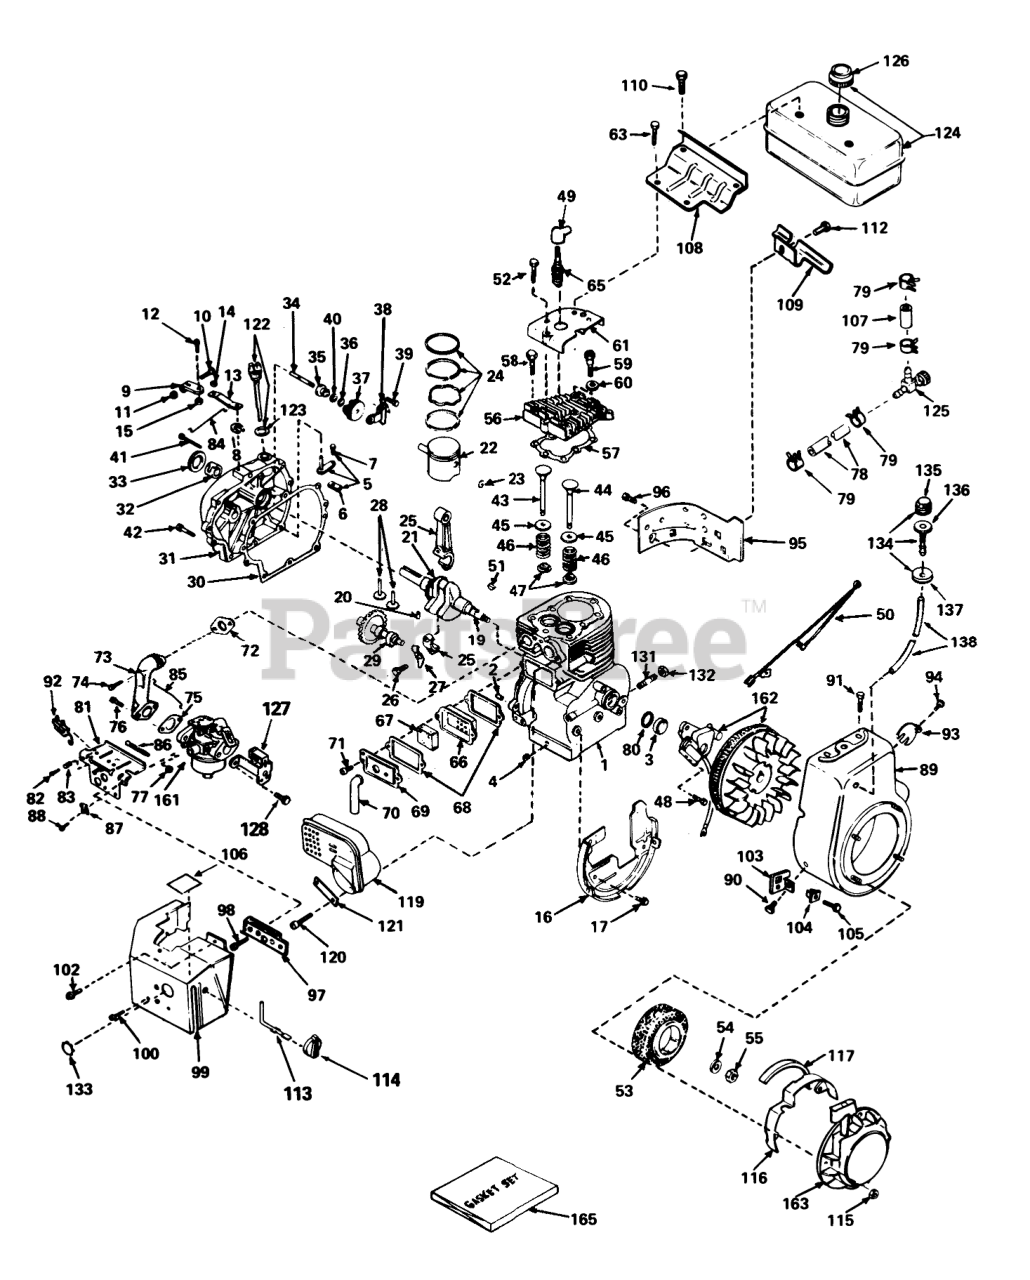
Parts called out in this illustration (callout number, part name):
1	Cylinder Assembly (Incl. Ref. #2, 3 & 4)
2	Pin-Dowel
3	Oil Seal
4	Plug-Drain, Oil (SQH 1/4-18)
5	Rod Assembly, Governor (Incl. Ref. #6 & 7)
6	Yoke-Governor
7	Screw (6-40x5/16)
8	Ring-Retaining
9	Clamp-Lever, Governor
11	Nut-Lock
12	Screw
13	Lever-Governor
14	Washer-Lock
15	Nut-Lock
16	Baffle Blower Housing
17	Screw (1/4-20x19/32)
19	Crankshaft Assembly (Incl. Ref. #20 & 21)
20	Pin, Groove
21	Gear, Crankshaft
22	Piston & Pin Assembly (Incl. Ref. #23) (Std.)
22	Piston, Pin & Ring Assy. (Incl. Ref. #23 & 24) (Std.)
22	Piston & Pin Assembly (Incl.Ref . #23) (.010 Oversize)
22	Piston, Pin & Ring Assy. (Incl. Ref. #23 & 24) (.010 Oversize)
22	Piston & Pin Assembly (Incl. Ref. #23) (.020 Oversize)
22	Piston, Pin & Ring Assy. (Incl. Ref. #23 & 24) (.020 Oversize)
23	Ring-Retaining, Piston Pin
24	Ring Set (Std.)
24	Ring Set (.010" OS)
24	Ring Set (.020" OS)
25	Rod Assy., Connecting (Incl. Ref. #26 & 27)
26	Bolt, Connecting Rod
27	Dipper-Oil
28	Lifter-Valve
29	Camshaft (Mech. Comp. Release)
30	Gasket, Cylinder Cover
31	Cover, Cylinder (Incl. Ref. #32, 33 & 34)
32	Bushing, Crankshaft
33	Seal, Oil
34	Shaft-Governor
35	Spool-Governor
36	Ring-Retaining
37	Gear Assembly, Governor (Incl. Ref. #40)
38	Bracket-Gear, Governor
39	Screw (10-32 x 35/64)
40	Washer-Flat
41	Screw (1/4-20 x 1-1/4)
43	Valve, Intake (Std.)(Incl. Ref. #47)
43	Valve, Intake (1/32" Oversize) (Incl. Ref. #47)
44	Valve, Exhaust (Std.) Oversize) (Incl. Ref. #47)
44	Valve, Exhaust (1/32" Oversize) (Incl. Ref. #47)
45	Cap-Spring, Valve
46	Spring-Valve
47	Keeper-Spring, Valve
49	Cover-Spark Plug
50	Wire, Ground
51	Key-Flywheel
52	Screw (1/4-20 x 1/2)
53	Hub & Screen Assy., Starter
54	Washer
56	Head Cylinder
57	Gasket-Cylinder Head
58	Screw (5/16-18x1-1/2)
59	Screw (5/16-18x1-25/32)
60	Washer-Flat
61	Cover, Cylinder Head
63	Screw
65	Plug, Spark (J17LM or equiv.)
65	Plug, Spark (Champion RCJ-8)
66	Body-Breather
67	Element-Breather
68	Gasket-Breather
69	Cover-Valve
70	Tube-Breather
72	Gasket-Intake
73	Pipe-Intake
74	Screw (T-30, 5/16-18x1-3/32)
75	Gasket, Carburetor
76	Screw (1/4-28x1)
77	Nut and Lock Washer (1/4-28)
78	Line-Fuel
79	Clamp-Line, Fuel
80	Gasket Stator
81	Control Assy., Speed (Incl. Ref. #82, 83, 86 & 92)
82	Screw
83	Spring-Compression
84	Link, Governor
85	Link-Throttle
86	Spring, Extension
87	Conduit
88	Screw (10-32 x 3/8)
89	Housing, Blower
90	Screw, Hex Hd.
91	Screw (5/16-18x3/4)
92	Terminal Assembly
94	Screw (8-32 x 3/8)
95	Extension, Blower Housing
97	Bracket-Carburetor
98	Screw (8-32x27/64)
99	Cover, Carburetor
100	Screw (10-32 x 3/8)
102	Screw (10-32x1/2)
103	Bracket
104	Grommet
105	Screw
107	Line-Fuel (8.62)
108	Plate, Fuel Tank Mounting
109	Bracket-Tank, Fuel
110	Screw (1/4-15x7/8)
112	Screw (1/4-20x19/32)
113	Rod-Choke
114	Knob-Control
115	Nut and Lock Washer (1/4-28)
116	Guard, Starter
117	Seal, Snowguard
119	Muffler
120	Screw, Hex Hd.
121	Plate-Locking
122	Dipstick, Oil (Incl. Ref. #123)
123	Gasket
124	Tank Assy ., Fuel (Incl. Ref. #1261)
125	Valve-Shut Off
126	Cap, Fuel
127	Bracket-Choke
128	Screw (10-32 x 1/2)
134	Primer Assembly (Incl. Ref. #135, 136 & 137)
135	33164A GILO"HITCH A
136	Body Primer
137	Retainer, Primer Bulb
138	Line, Primer
161	Carburetor (Incl. Ref. #75)
162	Magneto (The complete magneto is not available as an assembly. The magneto number is shown for reference purposes only. Order component parts individually, as shown in parts list.)
163	Starter, Rewind
165	Gasket Set
